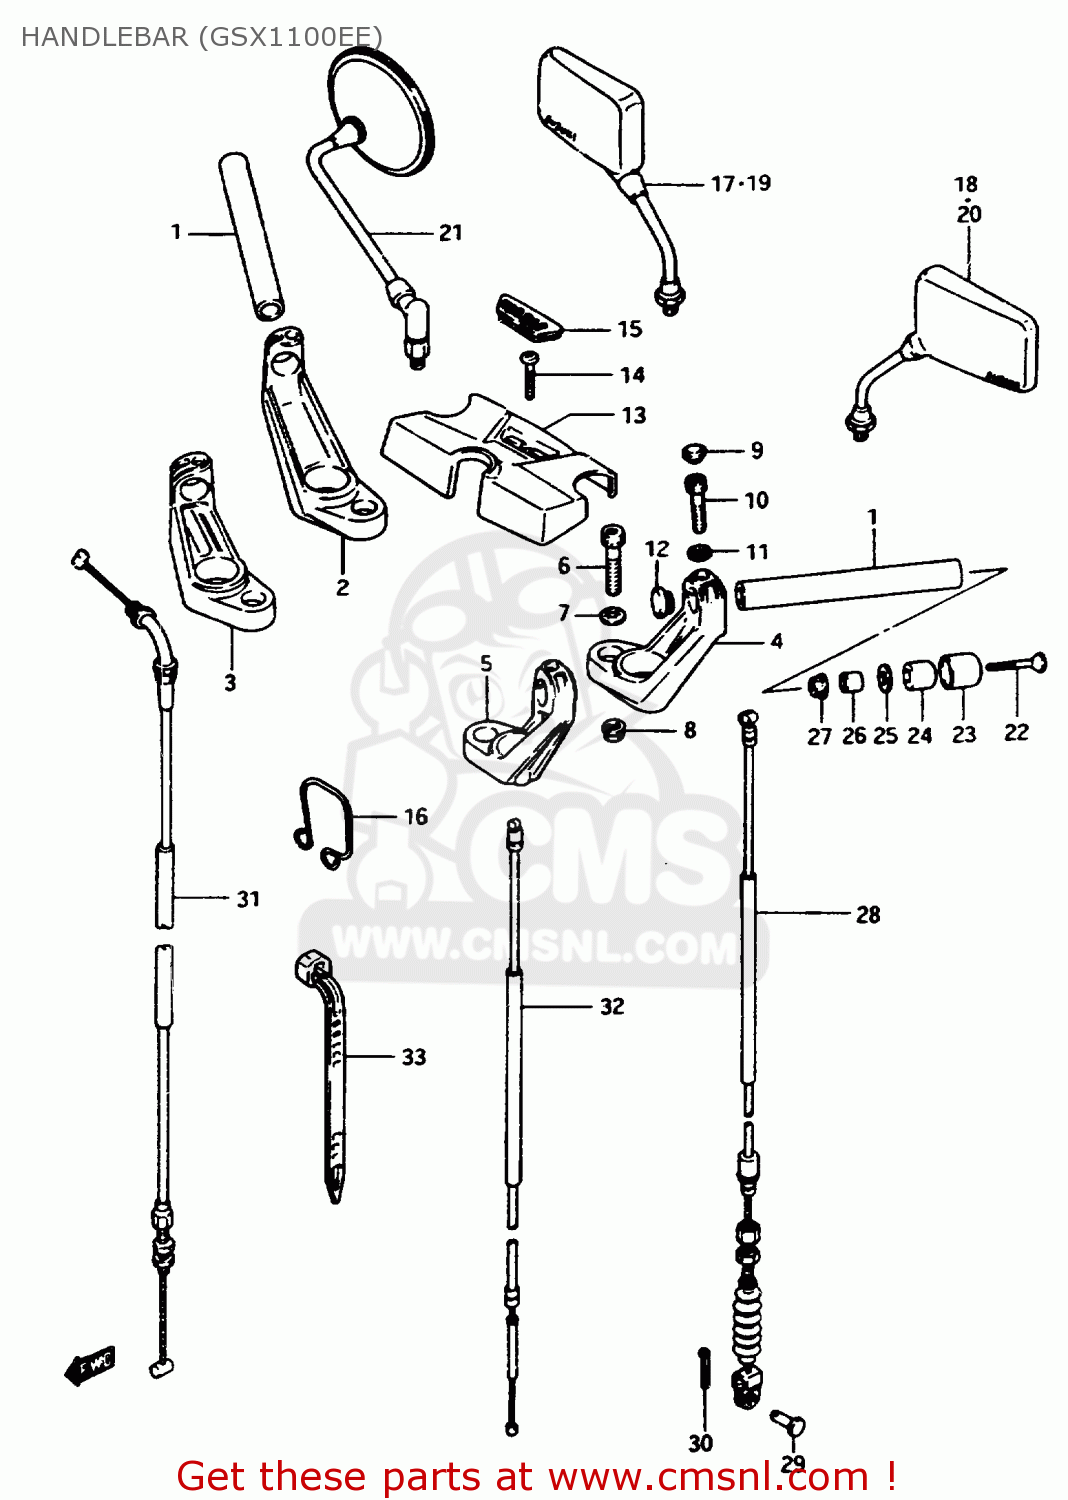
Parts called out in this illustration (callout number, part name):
1	HANDLEBAR
2	HOLDER,HANDLEBAR,RIGHT
3	HOLDER,HANDLEBAR,RIGHT
4	HOLDER,HANDLEBAR,LEFT
5	HOLDER,HANDLEBAR,LEFT
6	BOLT(10X50)
7	WASHER
8	NUT 10MM
9	CAP(OD:14.5)
10	BOLT 8X35
11	WASHER
12	CAP,GRIP END
13	PAD,HANDLE
14	SCREW
15	CAP,HANDLE PAD
16	GUIDE,CABLE/HARNESS
17	MIRROR ASSEMBLY,REAR VIEW
18	MIRROR ASSEMBLY,REAR VIEW
19	MIRROR, REAR VIEW RH
20	MIRROR, REAR VIEW LH
21	MIRROR ASSY,RH
22	SCREW 6X55
23	CAP,BALANCER
24	BALANCER,HANDLEBAR
25	SPACER,BALANCER
26	EXPANDER,BALANCER
27	NUT
28	CABLE ASSY,CLUTCH
29	PIN(L:15)
30	PIN
31	CABLE ASSY,THROTTLE
32	CABLE COMP,STARTER
33	CLAMP(L:165)
